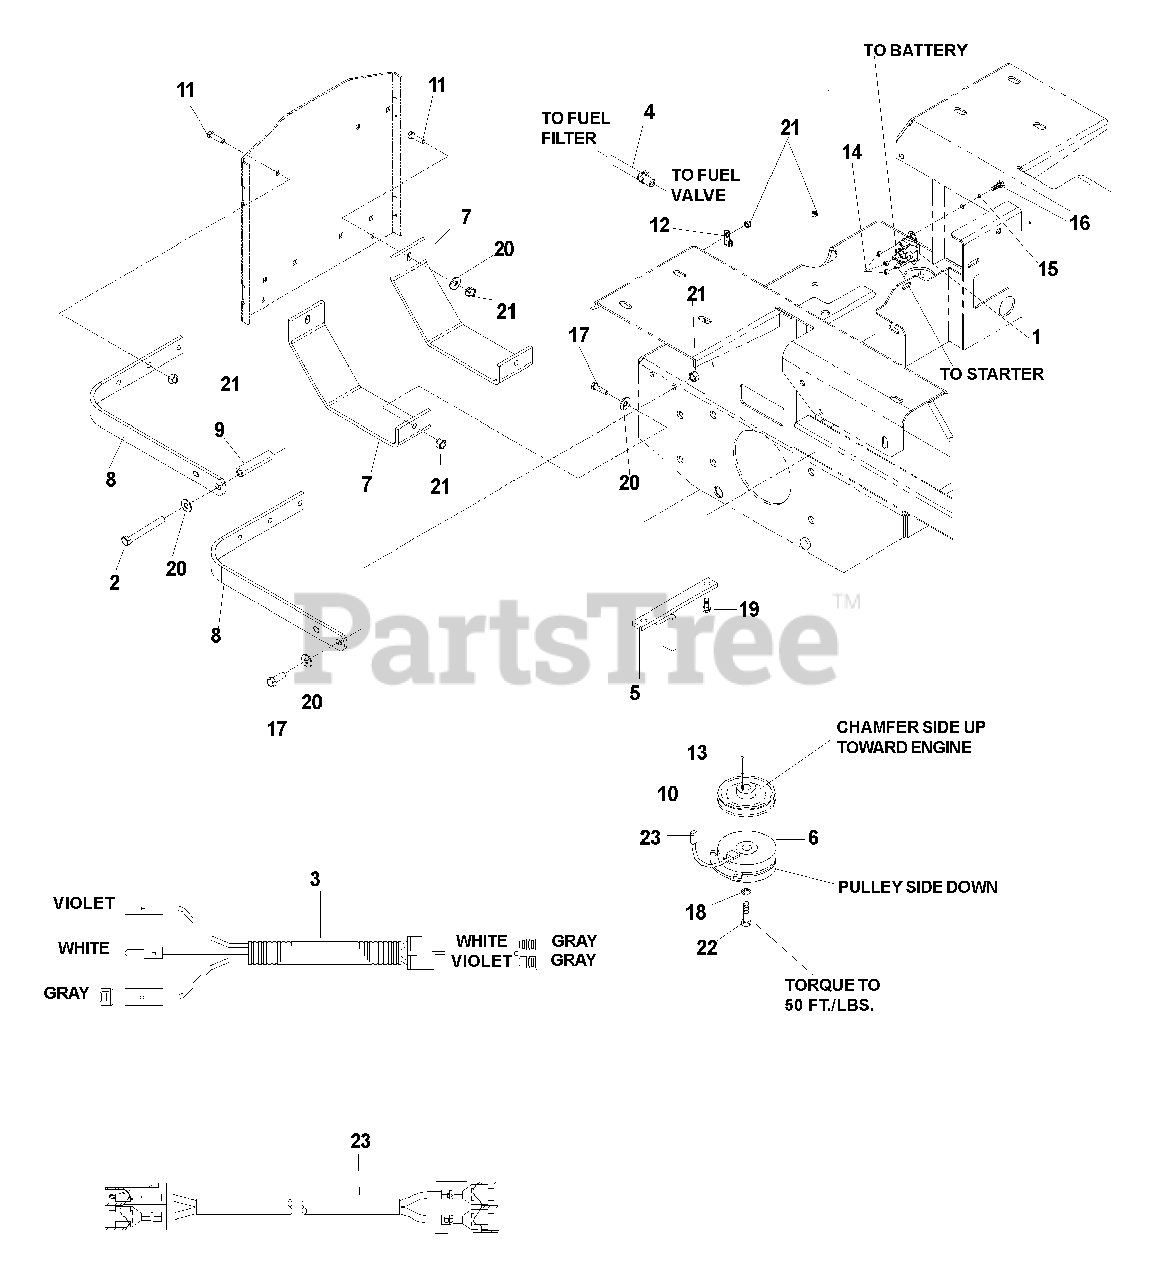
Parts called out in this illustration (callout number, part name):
2	HCS, 5/16-18 X 4, GR5
3	PIGTAIL, KAWASAKI
4	FUEL LINE HOSE
5	CLUTCH TIE DOWN
7	SKID PLATE
11	RHSNB, 5/16-18 X 1, GR5
12	CLAMP, DOUBLE TUBE
13	KEY, 1/4 SQ X 1 1/4
14	NUT, 1/4-20, NYLOC
15	WASHER, 1/4
16	HCS, 1/4-20 X 5/8, GR5
17	HCS, 5/16-18 X 1, GR5
18	LOCKWASHER, 7/16
19	HCS, 5/16-18 X 1 3/4, GR5
20	WASHER, 5/16
21	NUT, 5/16-18, NYLOC
22	HCS, 7/16-20 X 2 1/2, GR5
23	CLUTCH HARNESS
